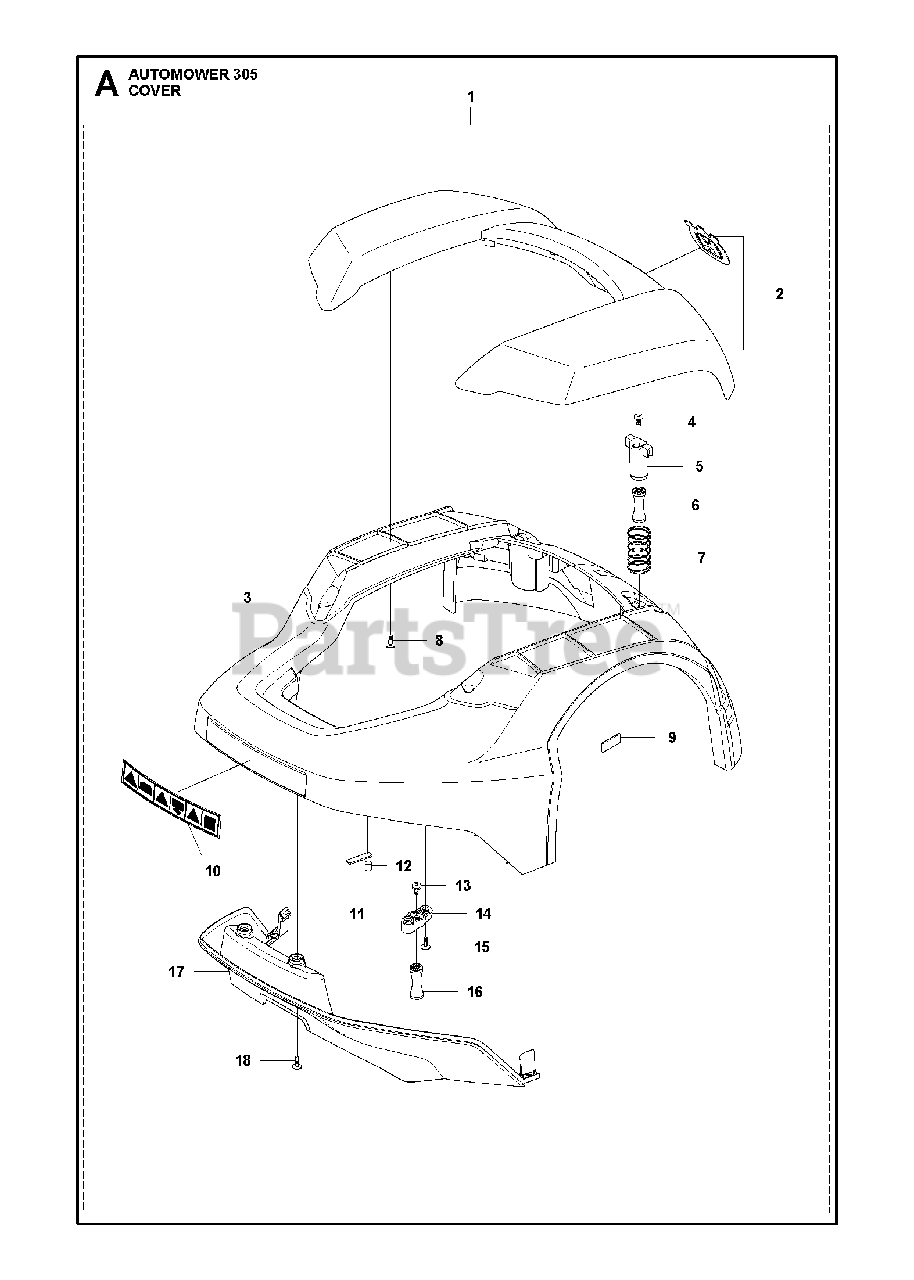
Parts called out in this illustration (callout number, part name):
4	SCREW ITXPANM M5X12 8
5	BRACKET COLUMN FRONT
6	DAMPER RUBBER 40 SHOR
7	SPRING LIFT SENSOR L
8	SCREW 14MM
9	MAGNET LIFT SENSOR
11	PLATE CARRIER MAGNET
12	MAGNET COLLISION SENS
13	SCREW ITXPANM M5X12 8
14	SUPPORT CLAMP USE WIT
15	SCREW 14MM
16	DAMPER RUBBER 40 SHOR
18	SCREW 14MM
